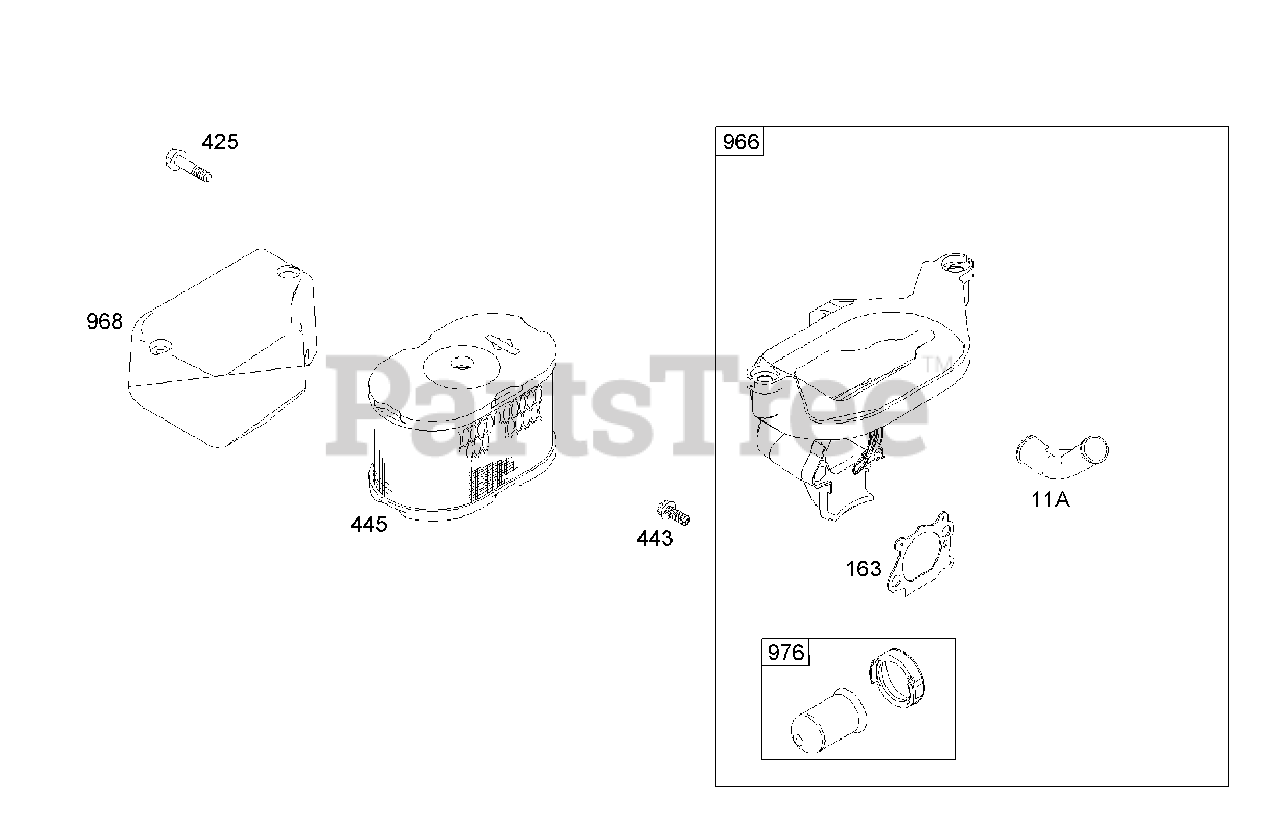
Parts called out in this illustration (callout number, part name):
11A	Tube-Breather
163	Gasket-Air Cleaner
425	Screw (Air Cleaner Cover)
443	Screw (Air Cleaner Primer Base)
445	Filter-Air Cleaner, Cartridge
966	Base-Air Cleaner Primer
968	Cover-Air Cleaner
976	Primer-Carburetor
